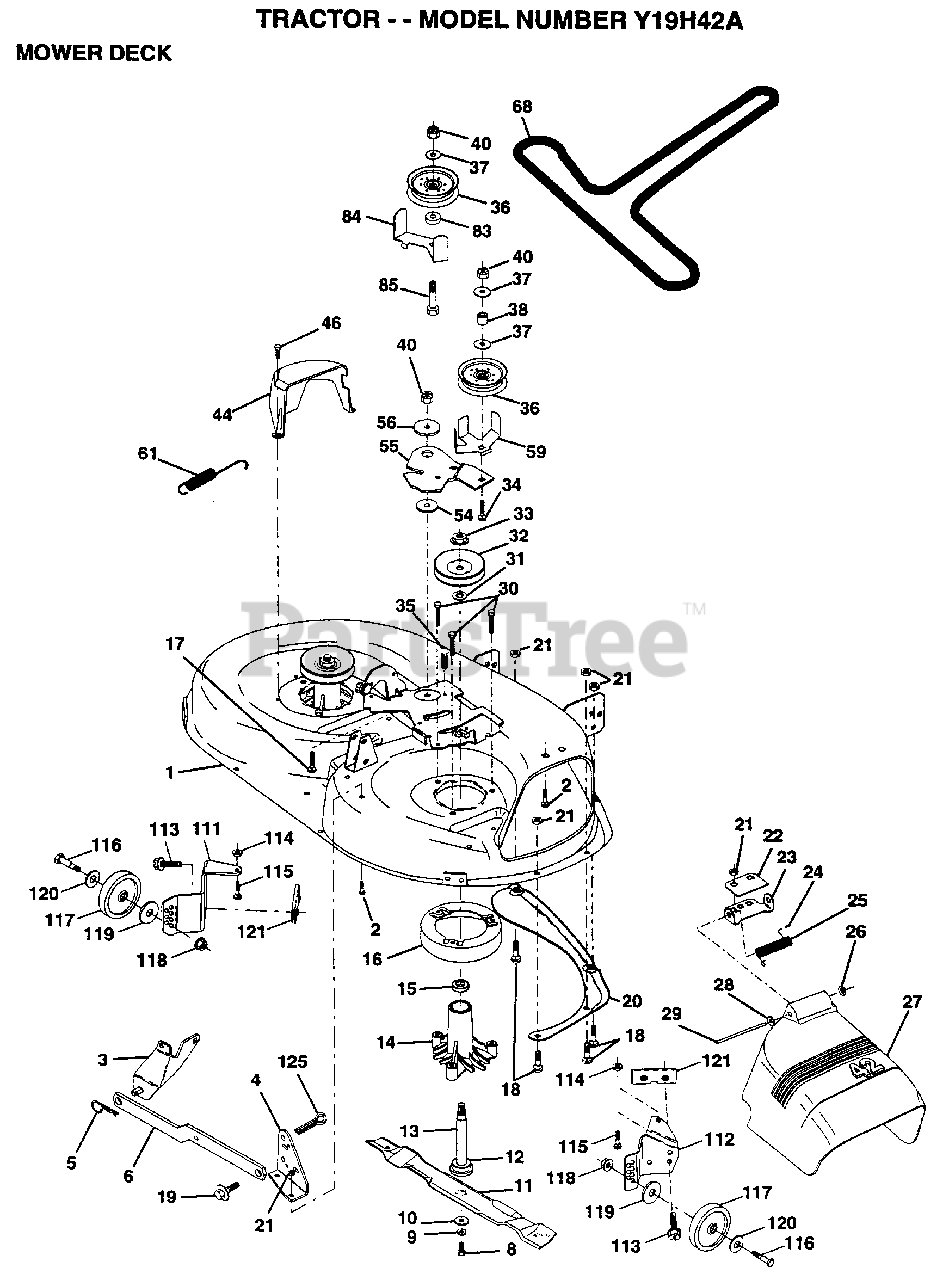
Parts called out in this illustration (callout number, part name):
1	DECK.WELD.42.
2	BOLT
3	BRKT ASM SWAY BAR
4	BRKT DECK SW BAR
8	BLADE BOLT
10	WASHER.HARD.BLADE
11	"BLADE.42"" HIPERF"
12	BEARING.BALL
14	HSG ASM MANDREL
15	BEARING
16	STRIPPER RND MWR
17	BOLT CARRIAGE
18	BOLT
19	BOLT SHD 5/16-18
22	STIFFENER BRKT
23	DEFLECTOR BRKT
24	CAP-SLEEV(107627)
25	SPRING.(150051)
26	NUT PUSH M
27	DEFLECTOR.SHIELD
28	WASHER
29	HINGE ROD
31	WASHER
34	BOLT
35	XMAS TREE FASTNER
36	FLAT IDLER PULLEY
37	WASHER
44	GUARD MAND LH BLK
46	SCREW.1/4-20X5/8
54	HARDENED WASHER
59	GUARD IDLER TUV
61	SPRING.EXTENSION
68	BELT.V.T-PATH
83	WASHER
85	BOLT
113	SCREW
116	BOLT M
117	WHEEL.GAGE.BLK.PL
118	LOCKNUT
119	WASHER
120	WASHER
121	BRACKET.EXTRD.GWL
125	COTTER PIN
